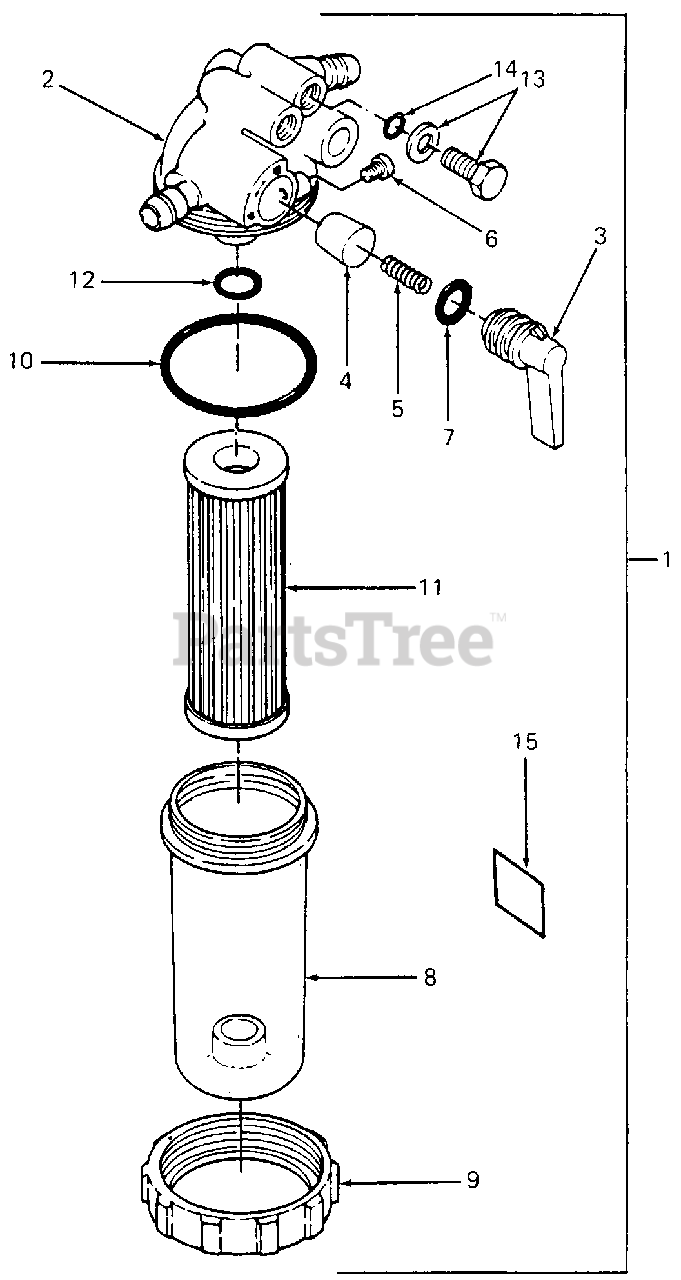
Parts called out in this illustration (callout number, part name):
1	Filter, Fuel
5	Spring, Valve
7	O-Ring, Lever
8	Cup, Filter
10	O-Ring, Filter Cup
11	Element
12	O-Ring, Filter
13	Plug, Breather
15	Label, Fuel Filter
